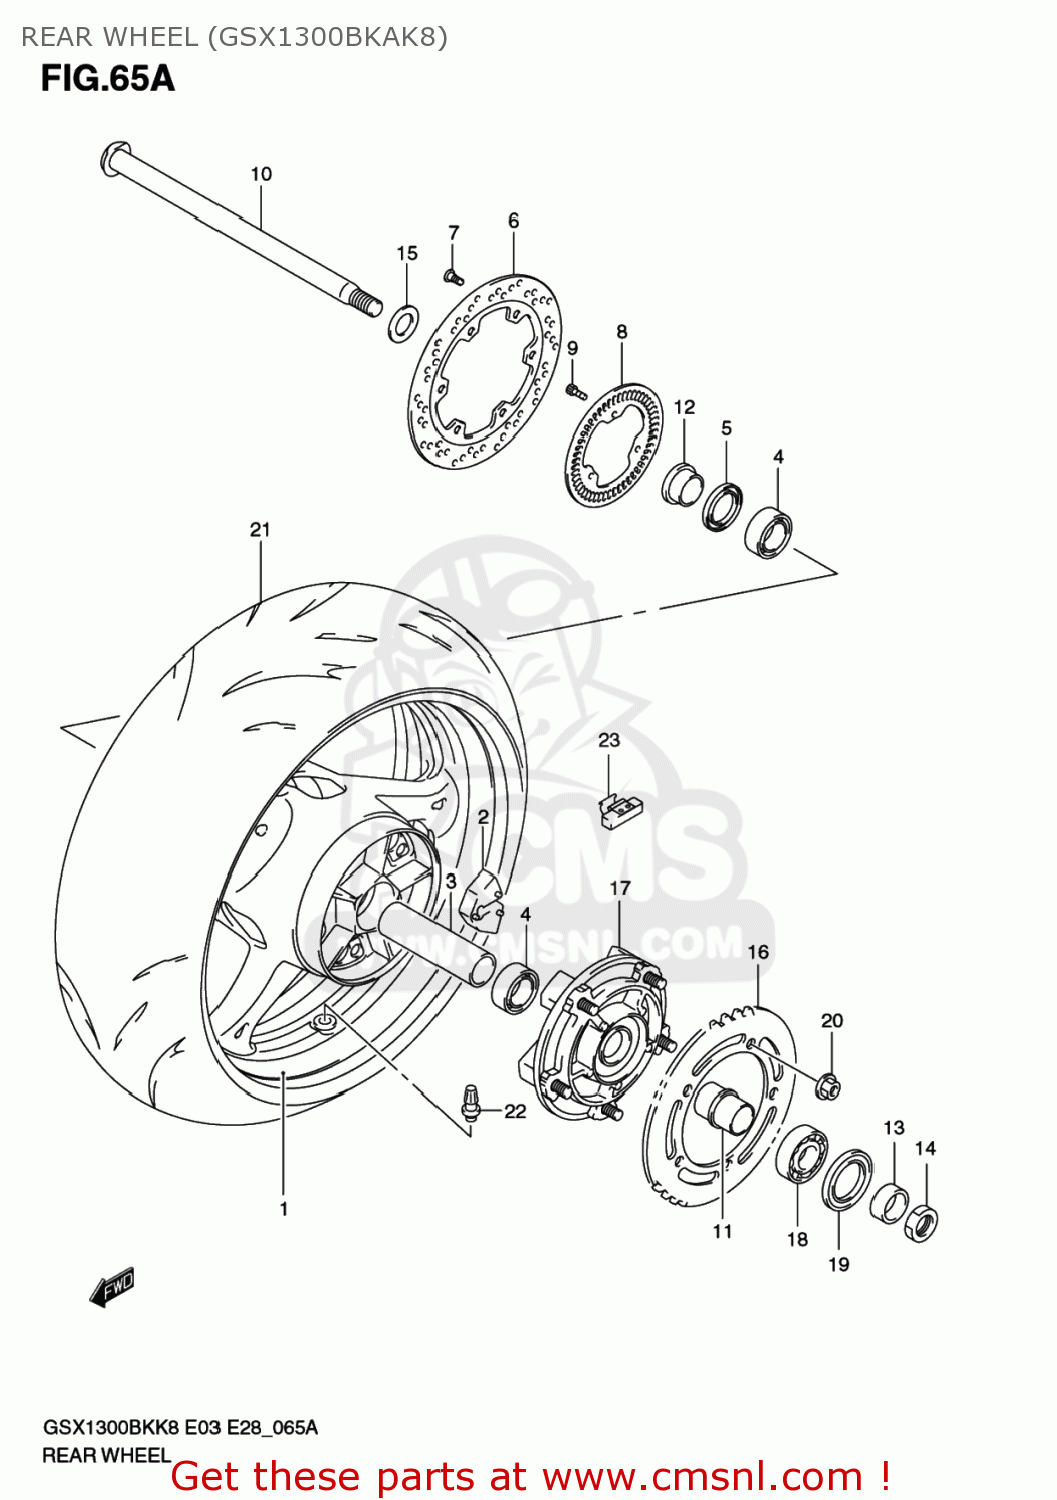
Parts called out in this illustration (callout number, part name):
1	WHEEL,RR(17M/CXMT6.00)
2	ABSORBER,RR HUB SHOCK
3	SPACER,RR WHEEL BEARING
4	BEARING(28X52X12)
5	SEAL,OIL(37X52X8)
6	DISC,RR BRAKE
7	BOLT(8X21)
8	RING,SPEED SENSOR RR(60T)
9	BOLT
10	AXLE,RR
11	RETAINER,RR SPROCKET DRUM
12	SPACER,RR AXLE,R
13	SPACER,RR AXLE,L
14	NUT
15	WASHER(25.2X42X3.2)
16	SPROCKET,REAR(
17	DRUM,RR SPROCKET
18	BEARING
19	SEAL,OIL(39X65X7)
20	NUT
21	TIRE,RR
22	VALVE ASSY,WHEEL RIM(TR412)
23	BALANCER,WHEEL(10G)
